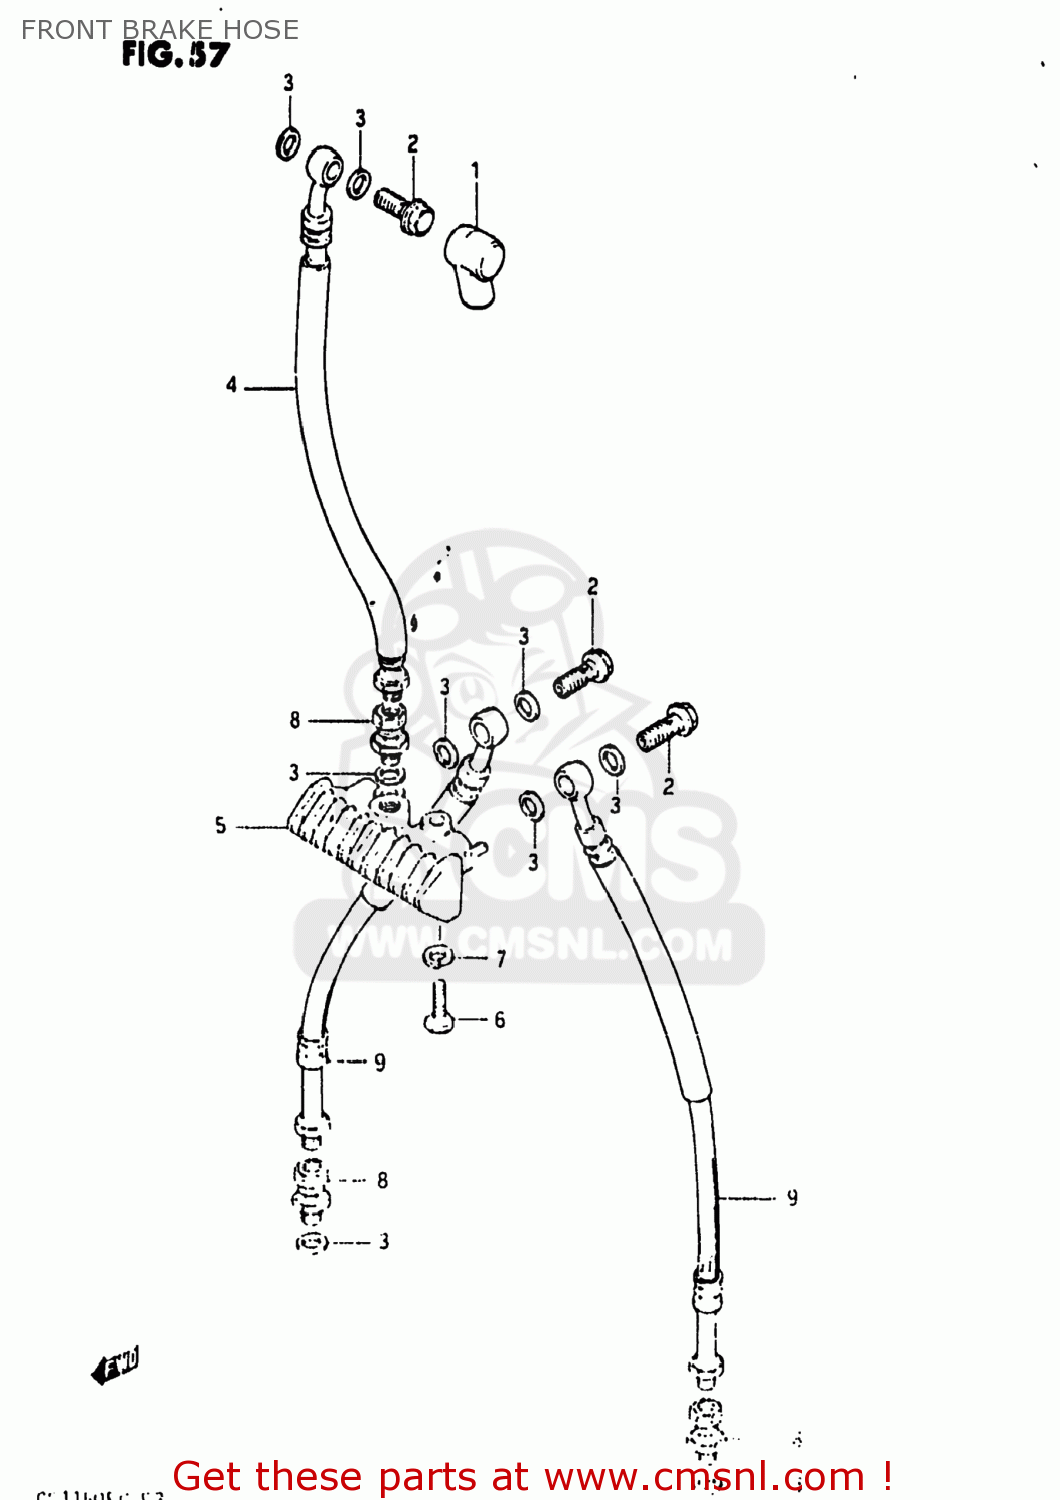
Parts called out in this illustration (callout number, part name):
1	BOOT,MASTER CYLINDER
2	BOLT UNION
3	WASHER(10X15X1.5)
4	HOSE,FRONT BRAKE
5	JOINT,BRAKE HOSE
6	BOLT
7	WASHER,LOCK
8	ADAPTER,BRAKE HOSE
9	HOSE,FRONT BRAKE NO.2
